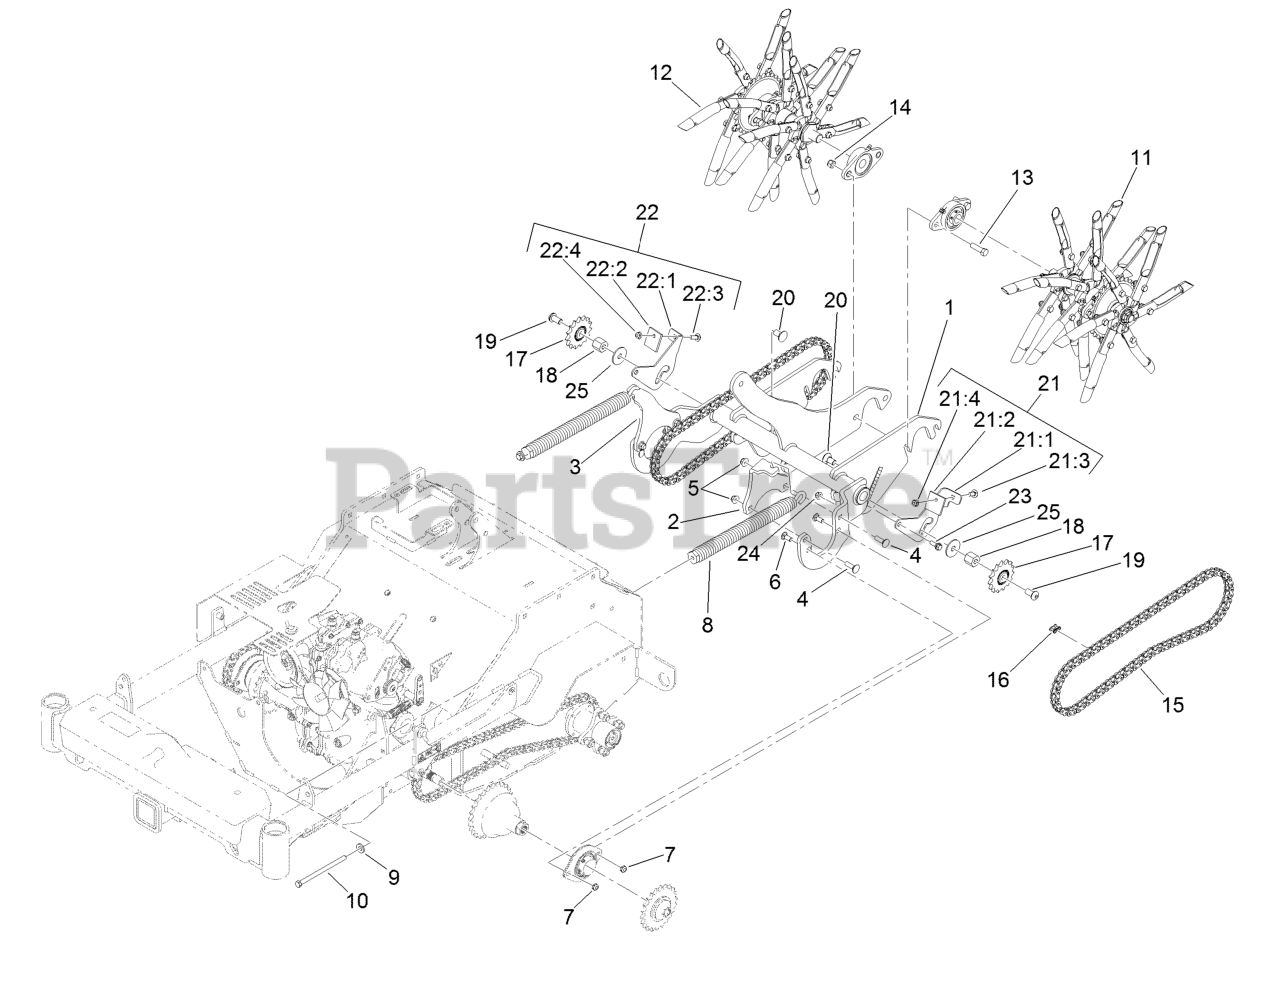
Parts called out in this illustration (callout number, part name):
1	Lift-Tine
2	Arm-Spring, LH
3	Arm-Spring, RH
4	Bolt-CARR
5	Nut-HF, NI
6	Bolt-CARR
7	Nut-Lock, NI
8	Spring-Extension
9	Washer-Belleville
10	Bolt-TAP, HH
11	LH Tine Wheel ASM
12	RH Tine Wheel ASM
13	Screw-HH
14	Nut-Lock, NI
15	Chain-Roller
16	Link-Connecting
17	Sprocket-Idler, 15T
19	Screw- Pan Socket Head
20	Screw-CARR
21	LH Debris Deflector ASM
21:1	Bracket-Deflector, Debris (LH)
21:2	Deflector-Debris
21:3	Bolt-CARR
21:4	Nut-HF, NI
22	RH Debris Deflector ASM
22:1	Bracket-Deflector, Debris (RH)
22:2	Deflector-Debris
22:3	Bolt-CARR
22:4	Nut-HF, NI
23	Screw-Shoulder
24	Nut-HF, NI
25	Washer-Flat
